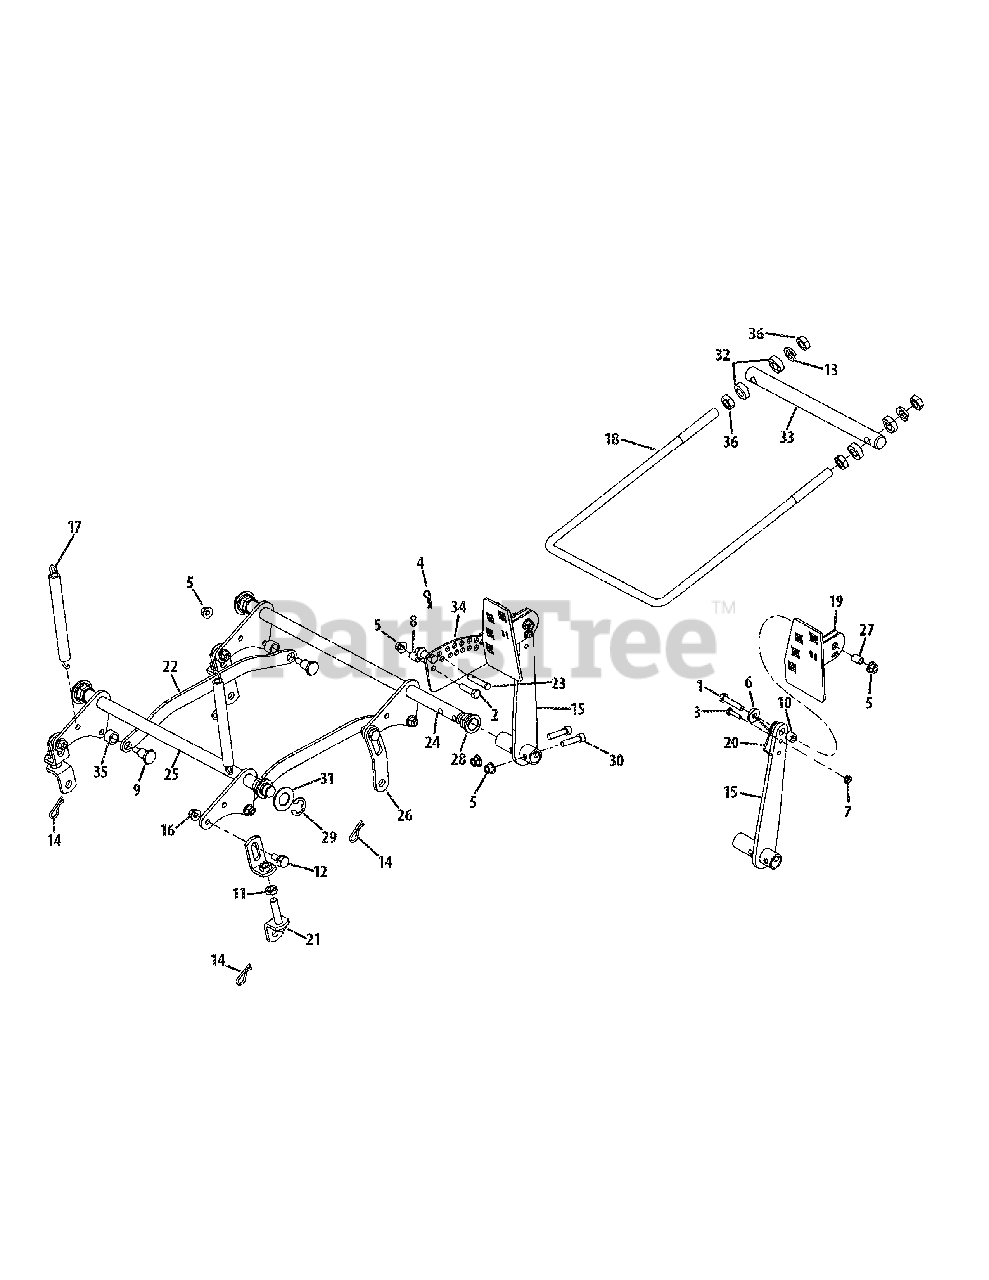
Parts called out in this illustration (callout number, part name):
1	Hex Screw, 3/8-16 x 1.75
2	Hex Screw, 3/8-16 x 1.50
3	Hex Screw, 1.4-20 x 1.00
4	Hair Pin, 3/8 x 1.562 x .080
5	Flange Counterlock Nut, 3.8-16
6	Washer, .390 x 1.00 x .180
7	Flange Toplock Nut, 1/4-20
8	Spacer, .375 x .500 x .750
9	Shoulder Bolt, 3/8-16 x .625 x .830
10	Spacer, .385 x .625 x .500
11	Jam Nut, 1.2-20
12	Shoulder Bolt, 3/8-16 x .56 x .27
13	Lock Washer, .633 x 1.07 x .161
14	Hair Pin, 1/2 x 1.625 x .125
16	Adjustable Deck Lift Bracket
17	Extension Spring, .75 x 7.89 x .14
18	Front Lift Rod
19	Foot Pedal Assembly
20	Torsion Spring, .900 x 2.3 x .09
21	Lower Bracket Assembly
22	Lift Connecting Link
23	Clevis Pin, 3/8 x 2.05
24	Front Shaft Assembly
25	Rear Shaft Assembly
26	Curved Link Plate
27	Spacer, .380 x .500 x .667
28	Hex Flange Bearing, 7/8
29	Retaining Clip, .675
30	Sockt Cap Screw, 3/8-16 x 1.50
31	Washer, .940 x 1.75 x .110
32	Spacer, .635 x 1.2 x .41
33	Trailing Link Pivot Rod
35	Spacer, 632 x .877 x .548
36	Jam Nut, 5/8-11
